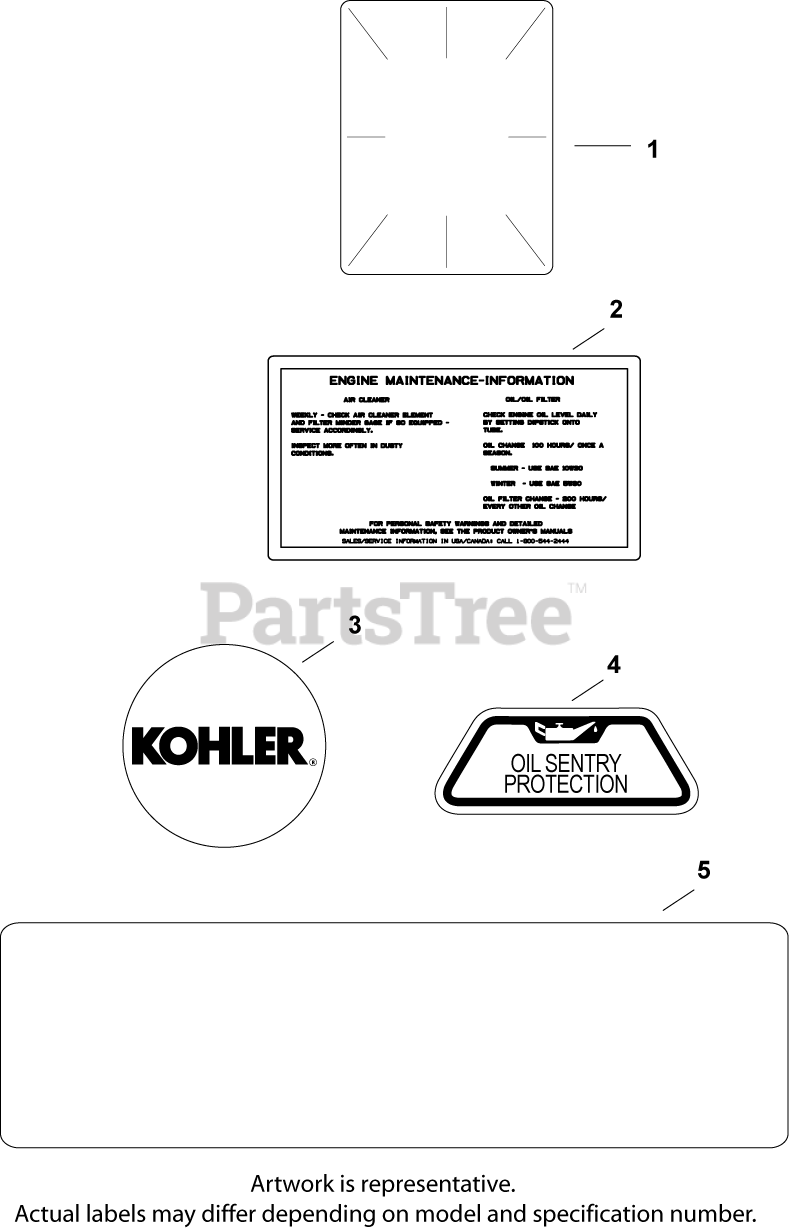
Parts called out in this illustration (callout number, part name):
1	DECAL, CLEAR LAMINATE USE 25 113 70-S
2	DECAL, AIR CLEANER - (#DSC)
3	LABEL, (ROUND KOHLER GOLD)-USE 24 113 18
4	DECAL, OIL SENTRY - (#DSC)
5	DECAL, 23 HP - (#24113216S)
